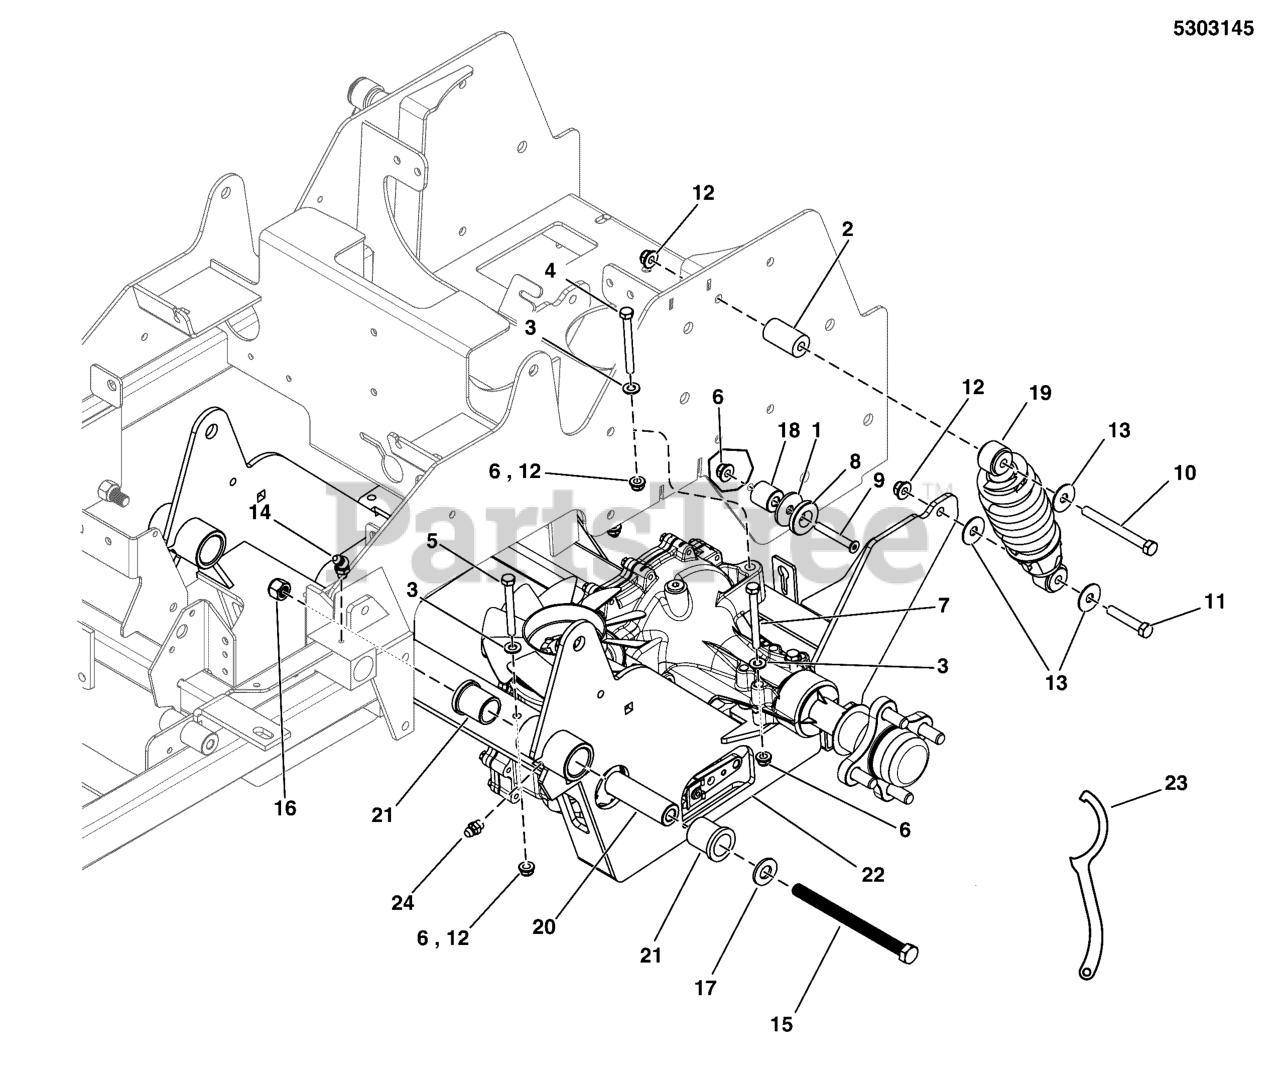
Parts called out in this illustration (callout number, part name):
1	WASHER, .390 X 1.50 X .109, YZ
2	SPACER, .390 X 1.00 X 1.00, CZ
3	WASHER, 5/16" SAE
3	WASHER, 3/8 SAE
4	BOLT, 5/16-18 X 2-1/2 GD5 YZ
4	BOLT, 3/8-16 X 2-1/2" GD5 CZ
5	BOLT, 5/16-18 X 2-3/4, GD 5, YZ
5	BOLT, 3/8-16 X 2-3/4" GD5 CZ
6	NUT, 5/16-18 HEX NYLOCK FLANGE
7	BOLT, 5/16-18 X 3 GD5 YZ
8	SPACER, .34 X 1.54 X .25 - UHMW
9	SCREW, 5/16-18X1.5, FLAT HD SOC, CZ
10	BOLT, 3/8-16 X 3" GD5 CZ
11	BOLT, 3/8-16 X 2, GD5, CZ
12	NUT, 3/8-16 HEX NYLOCK FLANGE
13	WASHER-3/8 FENDER
14	GREASE FITTING, 45 DEGREE
15	BOLT, 1/2-13 X 6-1/2 GD8, YZ
16	NUT, 1/2-13 HEX NYLON LOCK
17	WASHER, 1/2 SAE
18	SPACER, .39 X 1.00 X .50
19	SHOCK ABSORBER, IS600
20	SPACER, .52 X 1.00 X 3.42
21	BUSHING, FLANGE
22	CRADLE, Suspension
23	WRENCH, SPANNER, CZ
24	GREASE FITTING, 1/4-28 STRAIGHT
